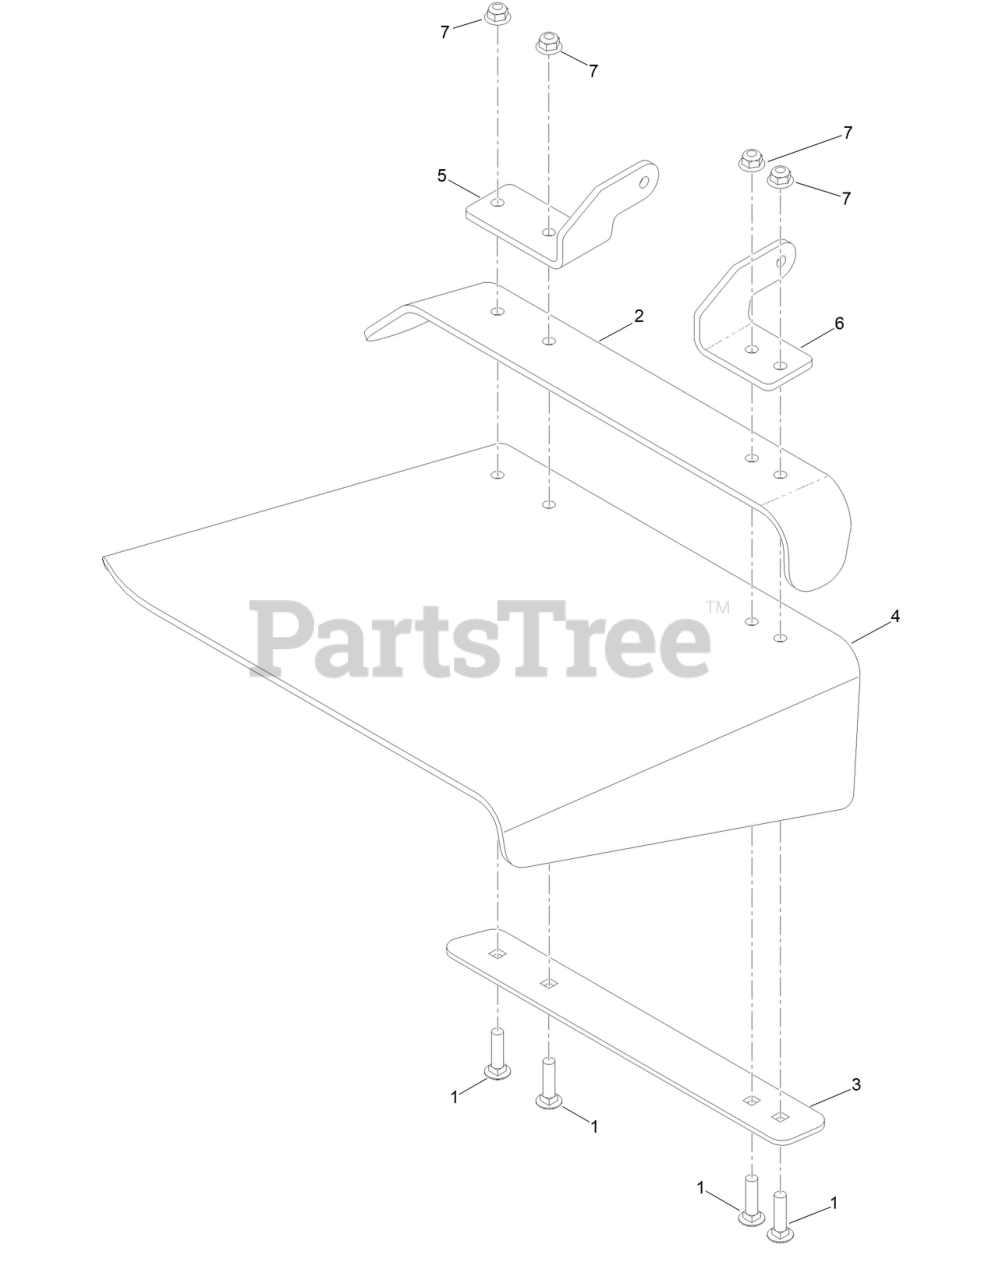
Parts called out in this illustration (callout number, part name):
1	SCREW-CARR
2	DEFLECTOR
3	STRAP-DISCHARGE
4	DEFLECTOR-DECK, RUBBER
5	PLATE-HINGE, REAR
6	PLATE-HINGE, FRONT
7	NUT-HF, NI
